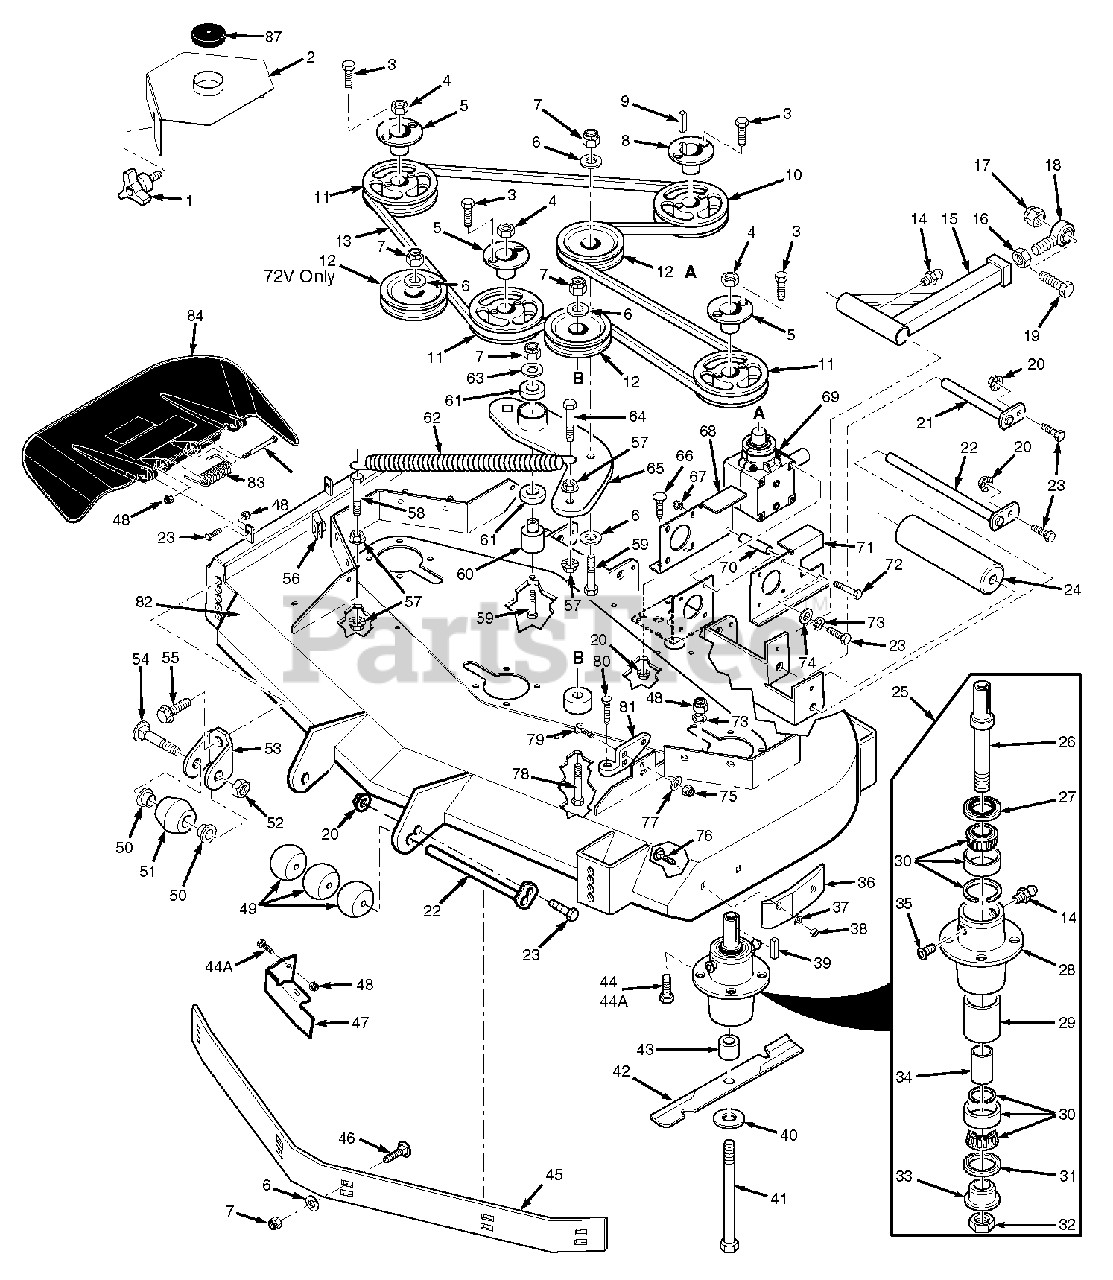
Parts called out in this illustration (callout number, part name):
1	Wing Nut, 3/8-16
2	Belt Cover Assembly
2	Belt Cover Assy., RH
2	Belt Cover Assy., LH
3	Bolt, Hex Head 1/4-20 x 1" Grd 8
4	Nut, 5/8-11 UNC
5	Tapered Hub, 1-1/8" Bore
6	Flatwasher, 3/8" (.391 x .938 x .105)
7	Nut, Hex Elastic Stop 3/8-16
8	Tapered Hub, 1" Bore
9	Key, 1/4 x 1/4 x 1-1/4"
10	Pulley, 6.75 O.D.
10	Pulley, 6.35 O.D.
11	Pulley, 6.35 O.D.
11	Pulley, 6.95 O.D.
12	Pulley, Idler
13	Belt, Cutter Deck Drive
14	Grease Fitting
15	Pusharm
16	Nut, Hex Head 5/8-18 UNF
17	Nut, Hex Elastic Stop 5/8-11
18	Rod End, 5/8" Male RH Thread
19	Bolt, Hex Head 5/8-11 x 4-1/2"
20	Nut, Hex Serrated Flange 5/16-18
21	Push Arm Shaft
22	Roller Shaft
23	Bolt, Hex Head 5/16-18 x 1-3/4"
24	Wheel, Anti-Scalp
25	Spindle Assembly
26	Spindle Shaft
27	Seal, Top
28	Spindle Housing
29	Spacer, Outside
30	Bearing Assembly
31	Seal, Bottom
32	Nut, Special 1-1/16-18
33	Spindle Bushing, Bottom
34	Spacer, Inside
35	Relief Fitting, Tapered Spindle
36	Wear Pad
37	Flatwasher, 5/16"
38	Nut, Center Lock 5/16-18
39	Key, 1/4 x 1/4 x 2"
40	Flatwasher, 5/8" Hardened
41	Bolt, Hex Head 5/8-11 x 9-1/2"
42	Cutter Blade, 21"
42	Cutter Blade, 21" (35BVAC)
42	Cutter Blade, 24.5"
43	Spacer, Spindle Bottom
44	Bolt, Hex Head 5/16-18 x 1-3/4"
45	Baffle, Custom Cut 61V
45	Baffle, Custom Cut 72V
46	Bolt, Carriage 3/8-16 x 1"
47	Discharge Baffle 61V
47	Discharge Baffle 72V
48	Nut, Hex Elastic Stop 5/16-18 Grd 8
49	Wheel, Anti-Scalp
50	Bushing, .376 I.D. Oilite
51	Anti-Scalp Wheel
52	Locknut, 3/8-16 Center Lock
53	Anti-Scalp Wheel Bracket
54	Bolt, Carriage 3/8-16 x 4"
55	Bolt, Hex Serrated Flange 3/8-16 x 1"
56	U-Nut, 3/8-16
57	Nut, Hex Serrated Flange 3/8-16
58	Bolt, Hex Head 3/8-16 x 1-1/2"
59	Bolt, Hex Head 3/8-16 x 3"
60	Pivot, Idler
61	Bearings, Ball
62	Spring, Cutter Deck
63	Flatwasher,3/8-.39 x .938 x .105 HD
64	Bolt, Hex Head 3/8-16 x 1-1/2" Grd 8
65	Idler Arm, Cutter Deck
66	Bolt, Carriage 5/16-18 x 3/4"
67	Nut, Elastic Stop 5/16-18
68	Mounting Plate, RH Gearbox
69	Gearbox Assembly, Deck Drive
70	Spacer, Gearbox Mount
71	Mounting Plate, LH Gearbox
72	Bolt, Hex Head 5/16-18 x 4-3/4"
73	Lockwasher, 5/16"
74	Flatwasher, 5/16" (.375 x .875 x .083)
75	Nut, Elastic Stop 7/16-14
76	Bolt, Carraige 5/16-18 x 3/4"
77	Flatwasher, 7/16-.500 x 1.25 x .083
78	Bolt, Hex Head 3/8-16 x 3-1/4"
79	Bolt, Carriage 7/16-14 x 1-1/4"
80	Bolt, Deck Adjust
81	Lever Assy, Deck Level
82	Cutter Deck 61 V w/Decals
82	Cutter Deck 72 V w/Decals
83	Spring, Discharge Chute
84	Discharge Chute Assembly
84	CA Discharge Chute Assembly
85	Bolt, Hex Head 5/16-18 x 4-1/2"
86	Bolt, Carriage 5/16-18 x 1-1/4"
87	Cap, Spindle
